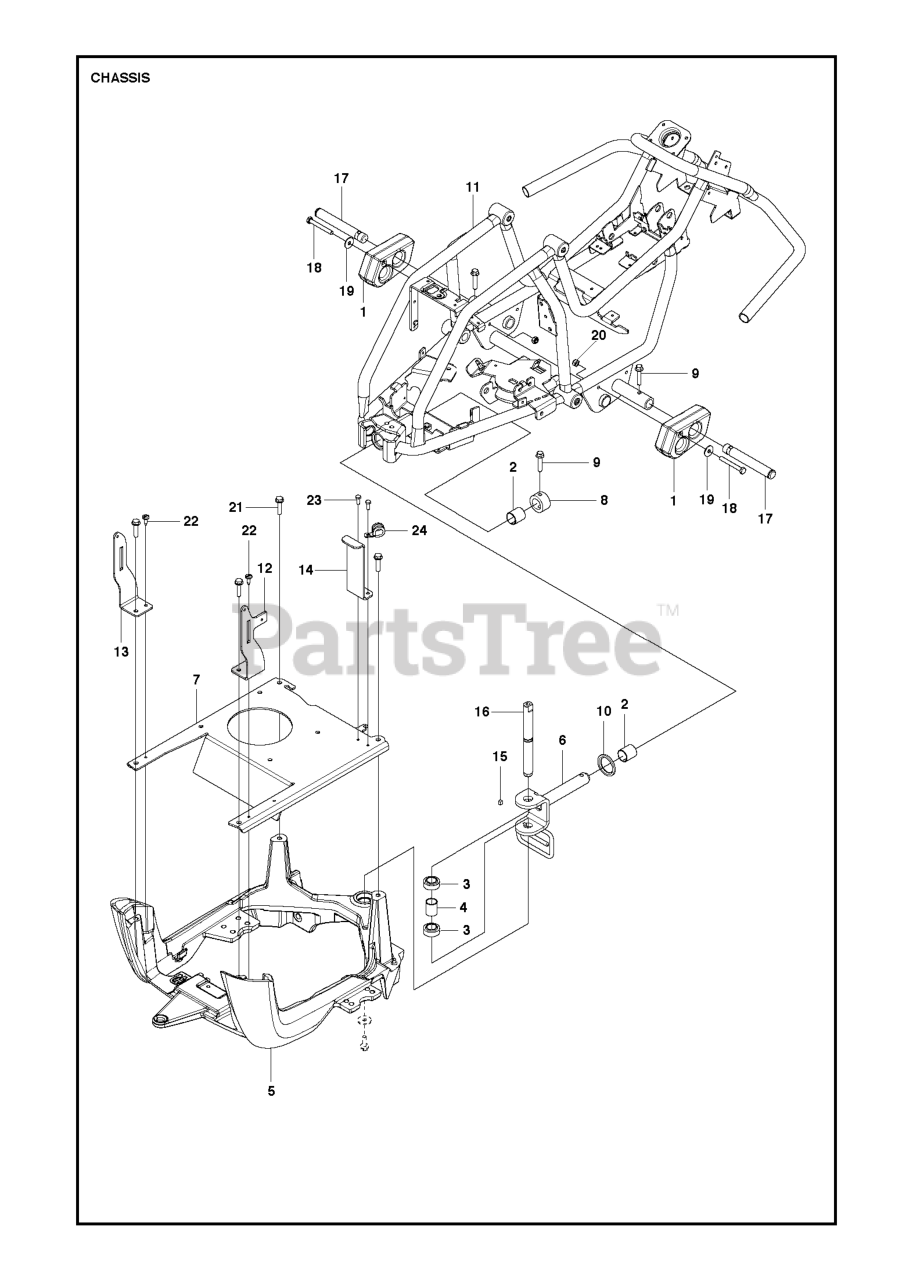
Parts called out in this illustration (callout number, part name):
1	COUNTERWEIGHT
2	BUSHING
6	SWING AXLE
8	STOP SLEEVE
9	BOLT FLANGE - M8X40\
11	FRAME FRONT ASSY
17	WHEEL AXLE
20	LOCKNUT M8
21	SCREW EHHFM
23	SCREW
24	HOSE CLAMP
